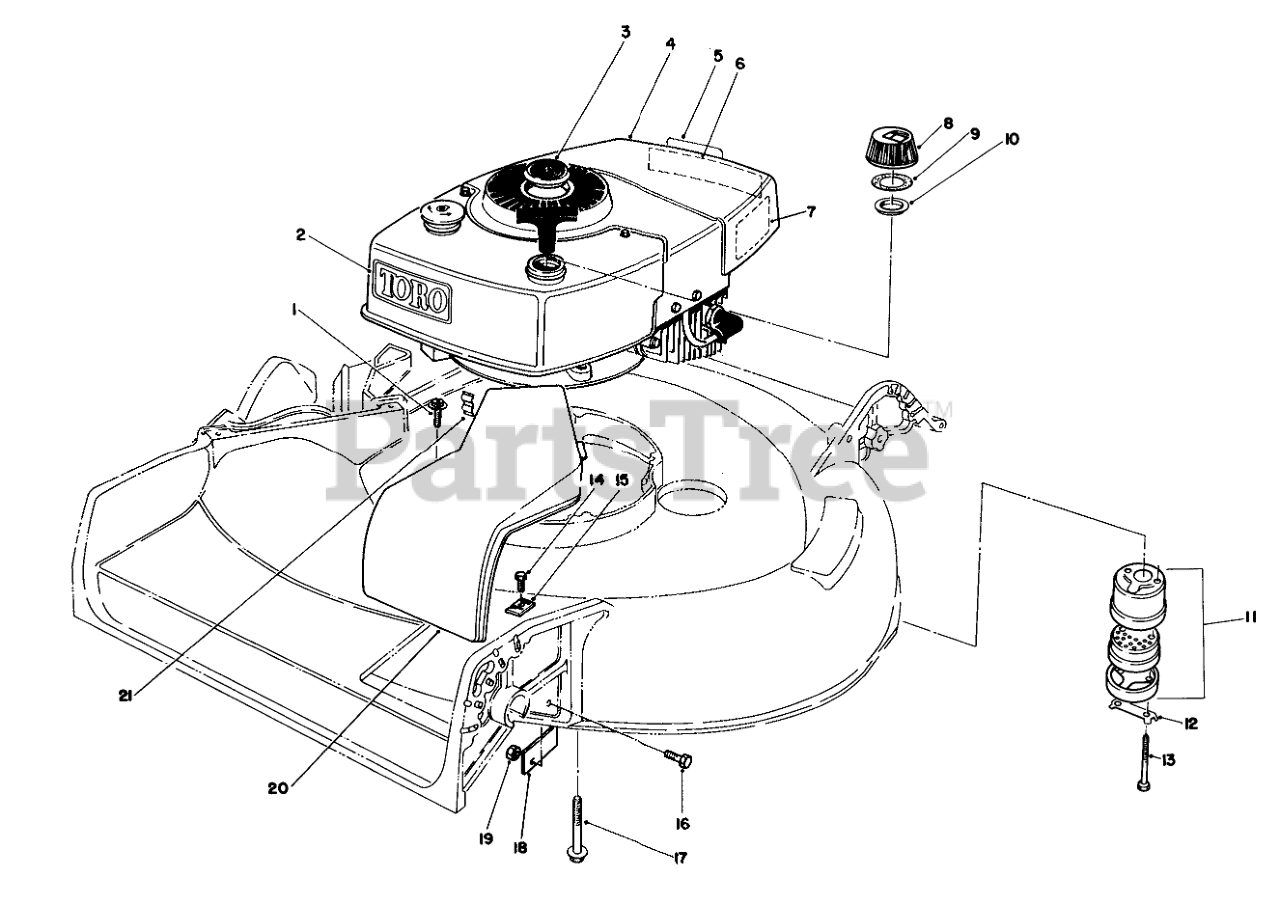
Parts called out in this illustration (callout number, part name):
1	SCREW
2	Decal Tow
3	Plug Button
5	DECAL-PRIMER
6	Decal Maintenance
7	Decal-Maintenance
8	Gas Cap Assembly (Incl. Ref. #9 & 10)
9	GASKET
10	GAS CAP BAFFLE
11	Muffler (Incl. Ref. #12 & 13)
12	CLIP - LOCKING
13	SCREW-HH
14	SCREW-HWHTF
15	Cable Clamp
16	SCREW-HH
17	3/8-16 X 2-3/4 CAPSCR
18	Shield Front
19	NUT-LOCK, NI
20	Cow-Belt
21	Clip Conduit
